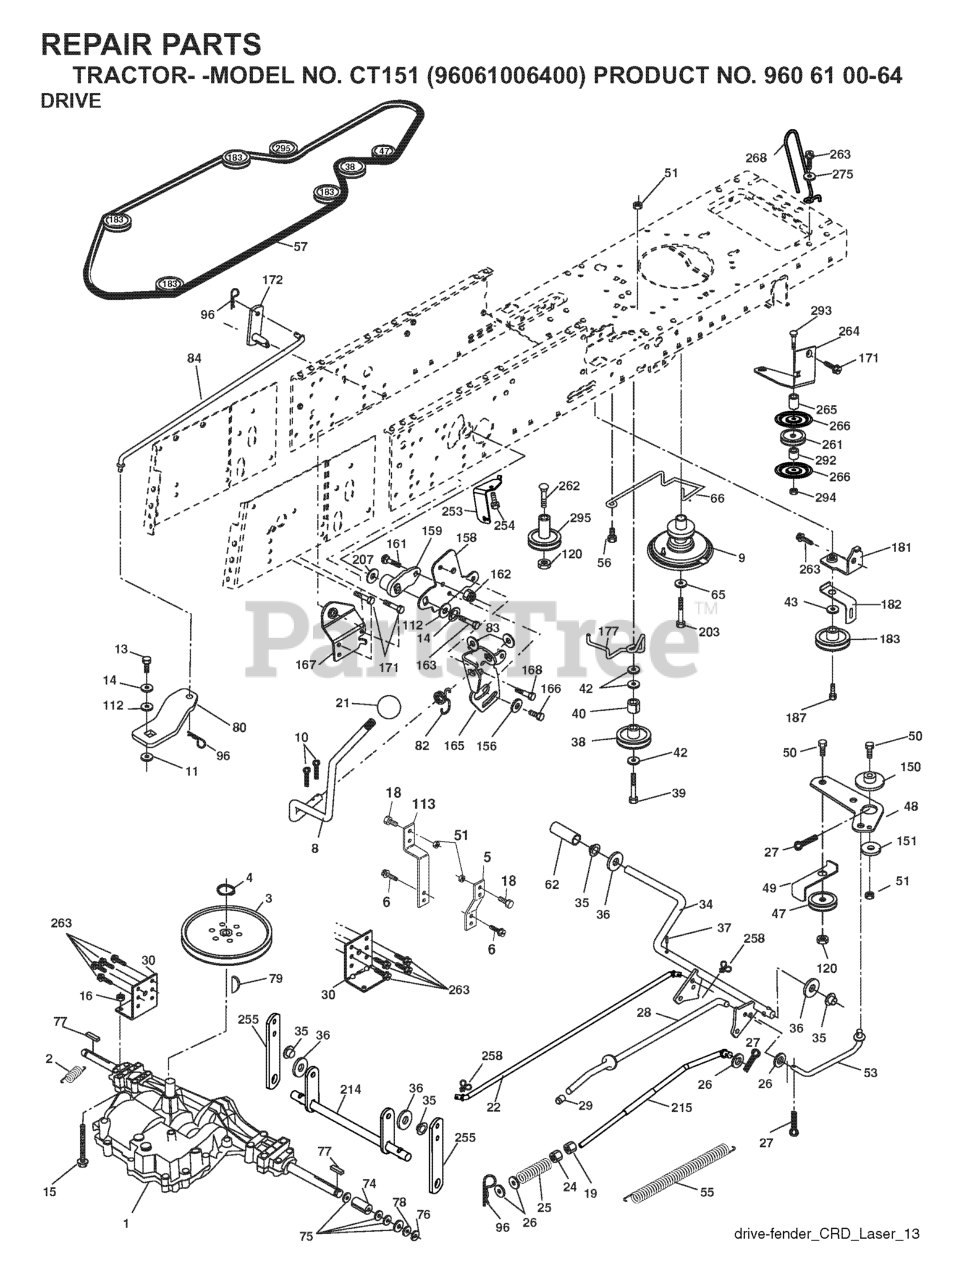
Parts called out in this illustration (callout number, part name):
2	SPRING,BRAKE RETURN
3	PULLEY
4	RETAINING RING LT
5	STRAP TORQUE
6	SCREW 5/16"
8	ROD SHIFT FENDER ADJUST LT
9	RP.CLUTCH.NORAM.2006.5
10	PIN COTTER
11	WASH-SHFT PLT LT
13	BOLT 1/4-28X3/4
14	LOCKWASHER
15	BOLT HEX 5/16-18 GR 5
16	NUT.71038.31-18.HEX.NYLOCK
19	NUT
21	KNOB.DUCKHEAD.1/2
22	ROD
24	NUT
25	SPRING ROD LT
26	WASHER
27	COTTER PIN
28	ROD, PARKING BRAKE
29	PLUNGER CAP
30	BRKT, MOUNT TRNSAXLE
34	SHAFT, FOOT PEDAL
35	BEARING.NYLON
37	DRIVE PIN
38	PULLEY.FLAT
42	WASHER
47	IDLER PULLEY
48	BELLCRANK, CLUTCH
49	RETAIN BELT
50	BOLT.3/8-16X1.50
53	LINK.CLUTCH.7.66.2005
55	SPRING, RETURN LT
56	SCREW.3/8-16
57	V-BELT.KEV.111"
62	COVER, PEDAL (1 2)
65	LOCKWASHER
66	KEEPER BELT ENGINE
74	SPACER AXLE
77	SQUARE KEY
79	KEY STD (1373) DANA
82	SHIFT SPRING
83	WASHER
96	RETAINER M
120	NUT LOCK FLG 3/8-16 UNC
150	BUSHING.BELLCRANK.GRD.DR
151	WASHER 12/32X2X10GA
156	WASHER.SRRTD.5/16
158	BRACKET
159	RB HUB.SHIFT
161	BOLT
162	NUT.CROWNLOCK.1/4
165	RP BRACKET
166	CAPSCREW.HXHD.FLG.5/16-18X.625
167	BRACKET.SUPT.SHIFT.CRD
168	BOLT.SHOULDER.5/16-18X
172	SHAFT
181	BRACKET
182	BELT GUIDE
183	PULLEY.V-IDLER.GRND.DR
187	BOLT.5/16-18X1.25
203	BOLT.HEX.7/16-20 X 5
207	WASHER NYL
214	LEVER
254	SCREW 3/8-16X1
255	SHAFT
258	CLIP RETAINER
261	FLAT IDLER PULLEY
263	SCREW, 3/8-16X3/4
265	SPACER IDLER
266	PROTECTOR
268	GUARD MUFFLER
275	WASHER
292	SPACER
293	BOLT.RDHD SQNK 3/8-16 X 3-1/2
294	NUT.HEX.3/8-16
295	PULLEY IDLER COMPOSITE
